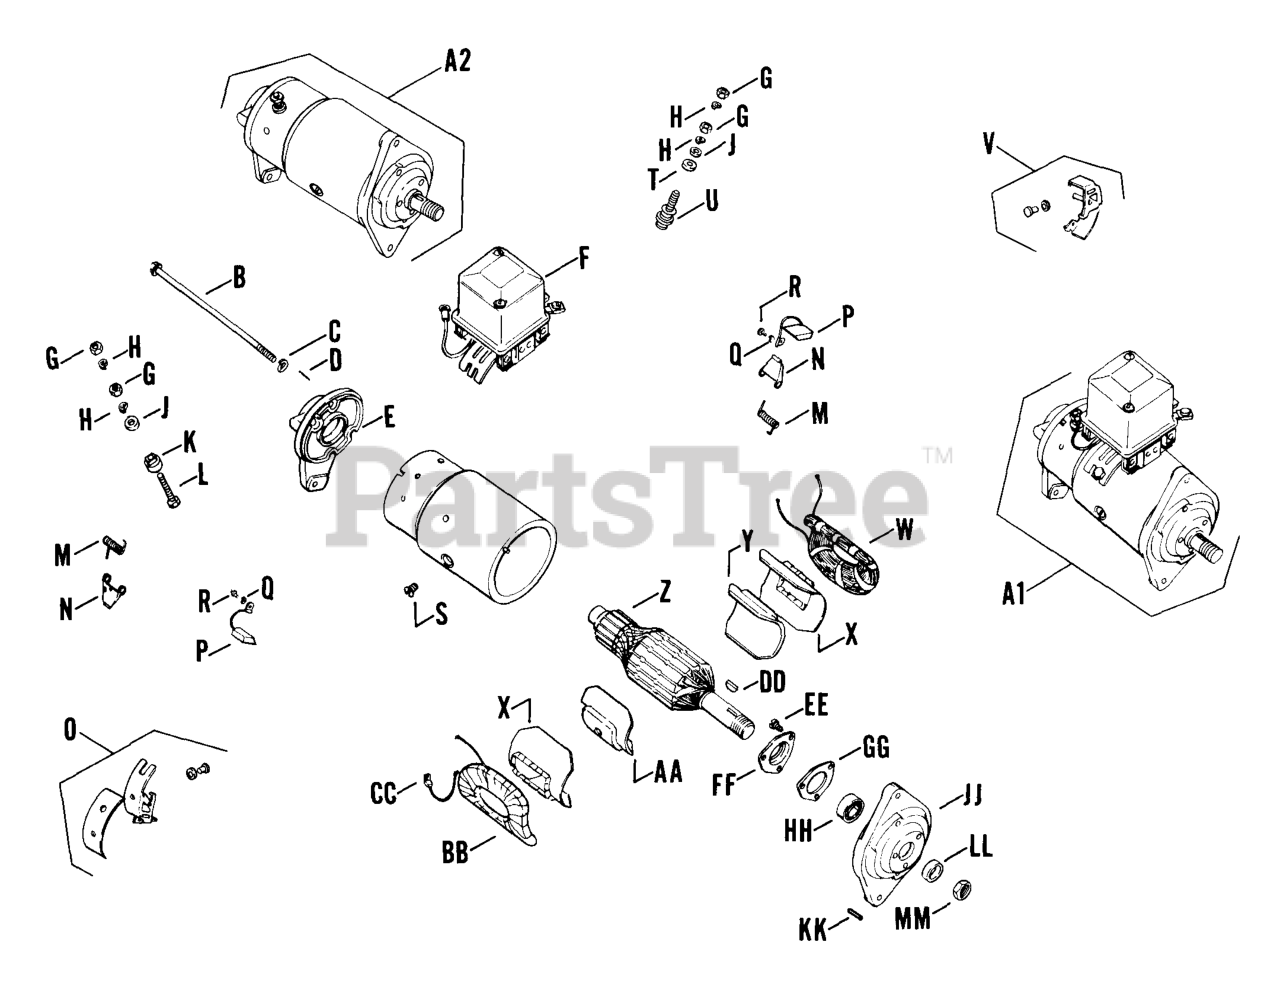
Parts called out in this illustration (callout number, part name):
A1	STARTER - DISCONTINUED
C	Washer, split - thru bolt
D	PIN - DISCONTINUED
E	FRAME - DISCONTINUED
F	REGULATOR - DISCONTINUED
G	NUT - DISCONTINUED
H	WASHER - DISCONTINUED
J	Washer, flat - terminal
K	BUSHING - DISCONTINUED
M	SPRING - DISCONTINUED
N	HOLDER - DISCONTINUED
O	HOLDER - DISCONTINUED
P	BRUSH - DISCONTINUED
Q	WASHER, SPRING LOCK #6
R	SCREW, SLT PAN HD 6-32X5/16" USE 25 086 57-S
S	SCREW - DISCONTINUED
T	WASHER - DISCONTINUED
V	HOLDER - DISCONTINUED
X	INSULATOR - DISCONTINUED
Z	ARMATURE - DISCONTINUED
AA	Shoe, pole plain
BB	COIL - DISCONTINUED
CC	CLIP - DISCONTINUED
DD	KEY - DISCONTINUED
EE	SCREW - DISCONTINUED
GG	GASKET - DISCONTINUED
HH	BEARING - DISCONTINUED
JJ	FRAME - DISCONTINUED
KK	PIN - DISCONTINUED
MM	NUT - DISCONTINUED
